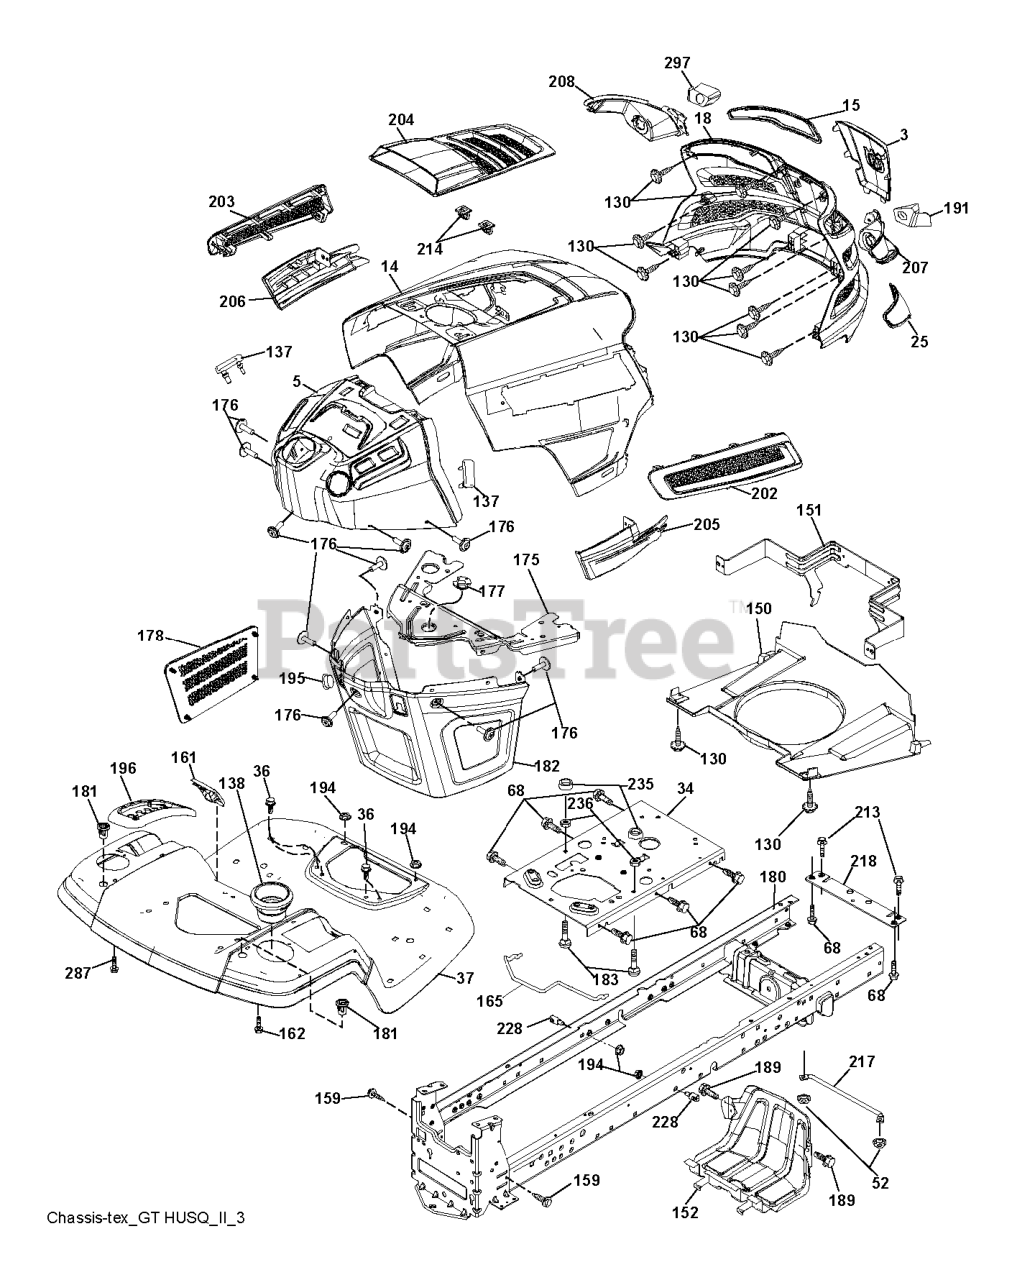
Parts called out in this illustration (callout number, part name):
3	APPLIQUE.SUBASM.GT.HUSQ.II
5	RP.DASH.UPP.GT2.SM.MC.CHOKE
14	HOOD.ASM.HUSQVARNA.GT.TEX.ORAN
15	LENS.HEADLIGHT.LH.GTII.2011
18	GRILLE.SUBASM.GT.HUSQ.II
25	LENS.HEADLIGHT.RH.GTII.2011
34	PLATE.ENGINE.WELDED.CHASSIS
36	SCREW 5/16"
37	Husqvarna TBD
52	LOCKNUT
68	Screw 5/16-18 x 1/2 Hex, Self Tapping 5/16-18 x 1/2
130	SCREW.#10 X 0.750.BOS
137	BUMPER DASH
138	HOLDER.CUP.LT.GREY
150	AIR.DUCT.GTV.BLACK
151	BRACKET.PIVOT.HOOD.GT.HUSQ.II
152	SHIELD.BROWNING.W/TEX
159	SCREW, 3/8-16X3/4
161	WINDOW.FUEL.LT.HUSQ.TEX.498
162	SCREW.HI-LO.CONSOLE
165	SUPPORT.TANK.REAR.W/TEX
175	PLATE.CROSSMEMBER.HUSQ
176	SCREW.#10-24X5/8.RN.QU
177	BUSHING, STEERING
178	CARGO.ASM.NET.TXGT.W/C
180	CHASSIS
181	BUSHING.MNT.FEND.CRGO.TEX.49
182	DASH.LOWER.COMMON.12V.ADAPTOR
183	BOLT.5/16-18X1-1/4 FULL THD
189	SCREW
191	INSERT.REFLECTIVE.RH.HUSQ.GTII
194	NUT LOCK HEX FLANGE 5/16-18
196	CONSOLE.ASM.DCKLFT.RBT.TLT.498
202	VENT.SIDE.RH.GT.HUSQ.II.
203	VENT.SIDE.LH.GT.HUSQ.II.498
204	VENT.TOP.HUSQ.GT2
205	SIDE.TRIM.RH.GT.HUSQ.II
206	SIDE.TRIM.LH.GT.HUSQ.II.GRAY
207	BEZEL LIGHT.RH.GT.II.MYLAR
208	BEZEL LIGHT.LH.GT.II.MYLAR
213	BOLT
214	CLIP.RETAINER.TINNER.
217	ROD.PIVOT.HOOD
218	X-PIECE.HOOD.STOP.NON/
228	STUD.FASTNER.W/ANTI-ROTATE
235	SPACER FENDER
236	NUT.CENTERLOCK.5/16-
287	SCREW 1/4X20
297	INSERT.REFLECTIVE.LH.HUSQ.GTII
